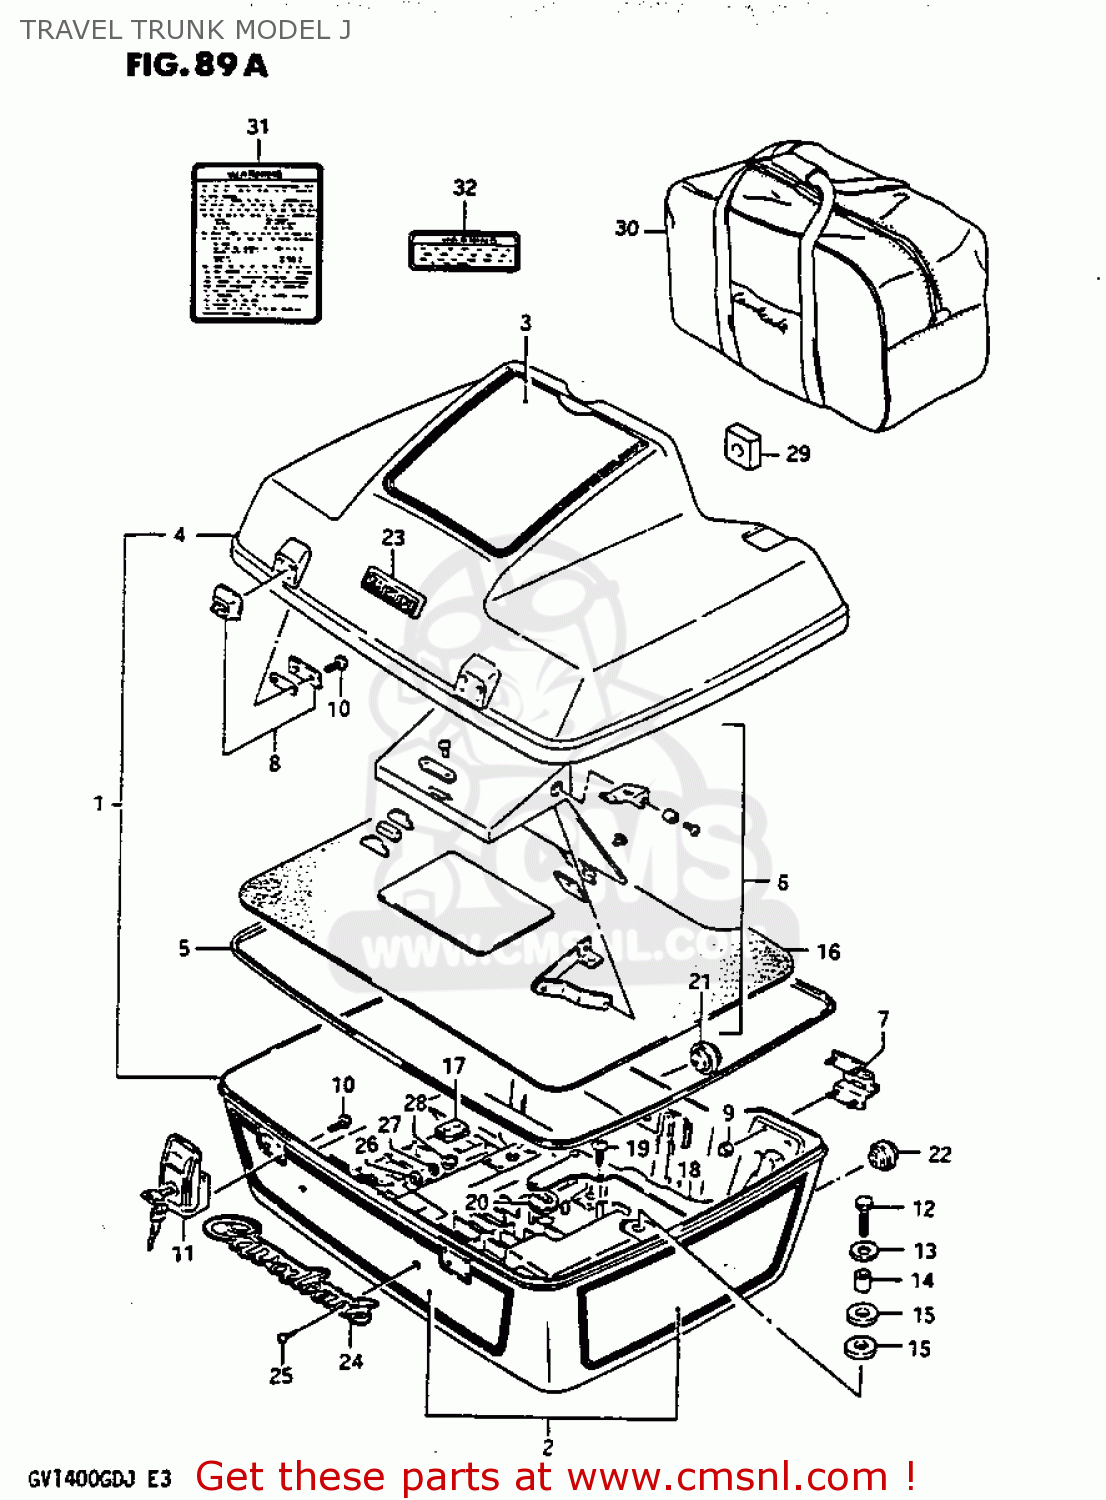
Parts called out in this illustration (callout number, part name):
1	TRUNK ASSEMBLY,TRAVEL
2	TAPE SET,TRAVEL TRUNK
3	TAPE SET,TRUNK LID STRIPE
4	LID,TRAVEL TRUNK
5	SEAL,TRAVEL TRUNK LID
6	MIRROR,TRAVEL TRUNK
7	HINGE,TRAVEL TRUNK
8	PLATE,TRUNK LID LOCK
9	NUT
10	SCREW
11	LOCK SET,SIDE BAG
12	BOLT
13	WASHER
14	SPACER(6.3X9.3X16.5)
15	CUSHION
16	SEAT,TRAVEL TRUNK BODY
17	GROMMET
18	COVER, AIR HOSE
19	SCREW
20	GROMMET
21	GROMMET
22	GROMMET
23	EMBLEM,TRAVEL TRUNK,UPPER
24	EMBLEM,TRAVEL TRUNK,LOWER
25	SCREW
26	WASHER
27	WASHER
28	NUT
29	SEAL
30	LUGGAGE BAG,TRAVEL TRUNK
31	LABEL (WARNING TRAVEL T
32	LABEL, WARNING
